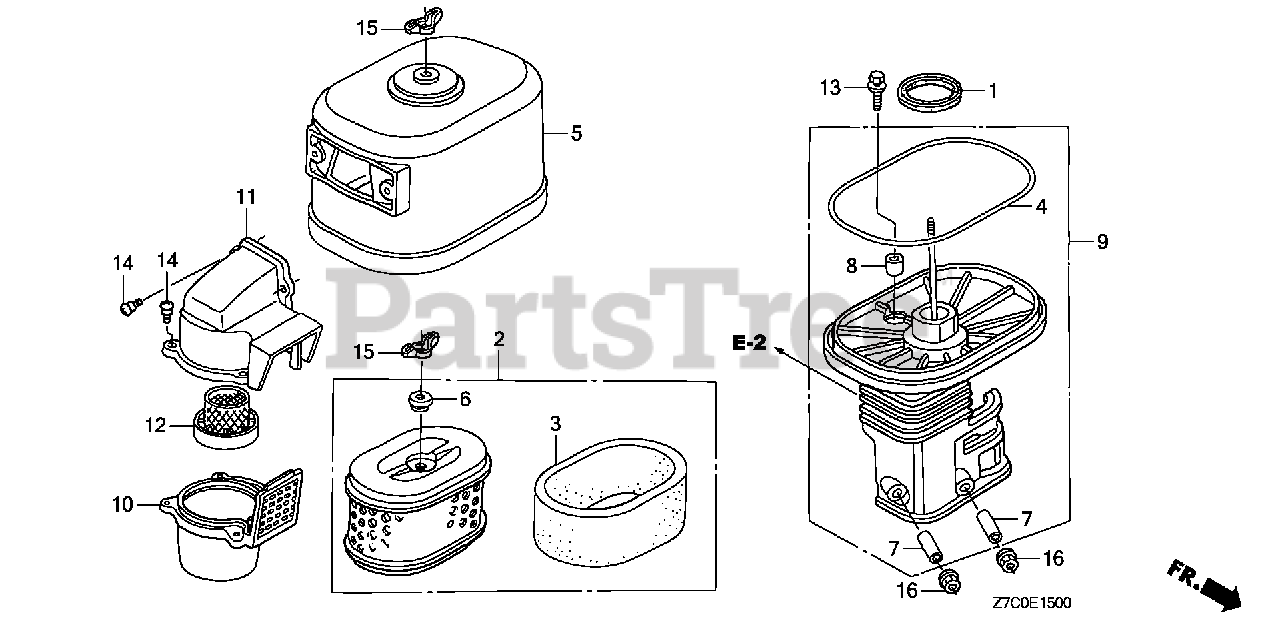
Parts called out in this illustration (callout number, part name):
1	GASKET, ELBOW
2	ELEMENT, AIR CLEANER
3	FILTER (OUTER)
4	SEAL, AIR CLEANER COVER
5	COVER, AIR CLEANER (CYCLONE)
6	GROMMET, AIR CLEANER
7	COLLAR, AIR CLEANER
8	COLLAR B, AIR CLEANER
9	ELBOW, AIR CLEANER
10	CASE, PRE AIR CLEANER
11	CAP, PRE AIR CLEANER
12	GUIDE, PRE AIR CLEANER
13	BOLT-WASHER (6X22)
14	SCREW, PAN (5X16.5)
15	NUT, TOOL BOX SETTING
16	NUT, FLANGE (6MM)
